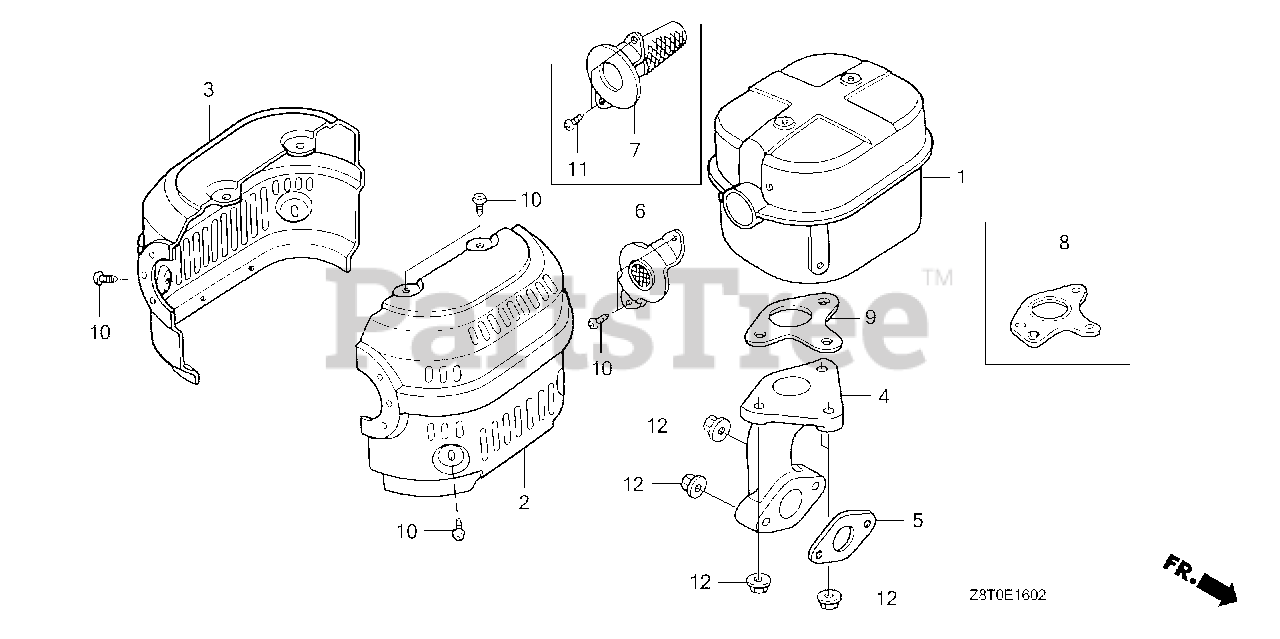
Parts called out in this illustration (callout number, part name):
1	MUFFLER
2	PROTECTOR, R. MUFFLER (ALUMINIZED)
3	PROTECTOR, L. MUFFLER (ALUMINIZED)
4	PIPE, EX.
7	ARRESTER, SPARK
8	GASKET, MUFFLER (ARRESTER)
10	SCREW, TAPPING (5X8)
11	SCREW, TAPPING (5X8)
12	NUT, FLANGE (8MM)
